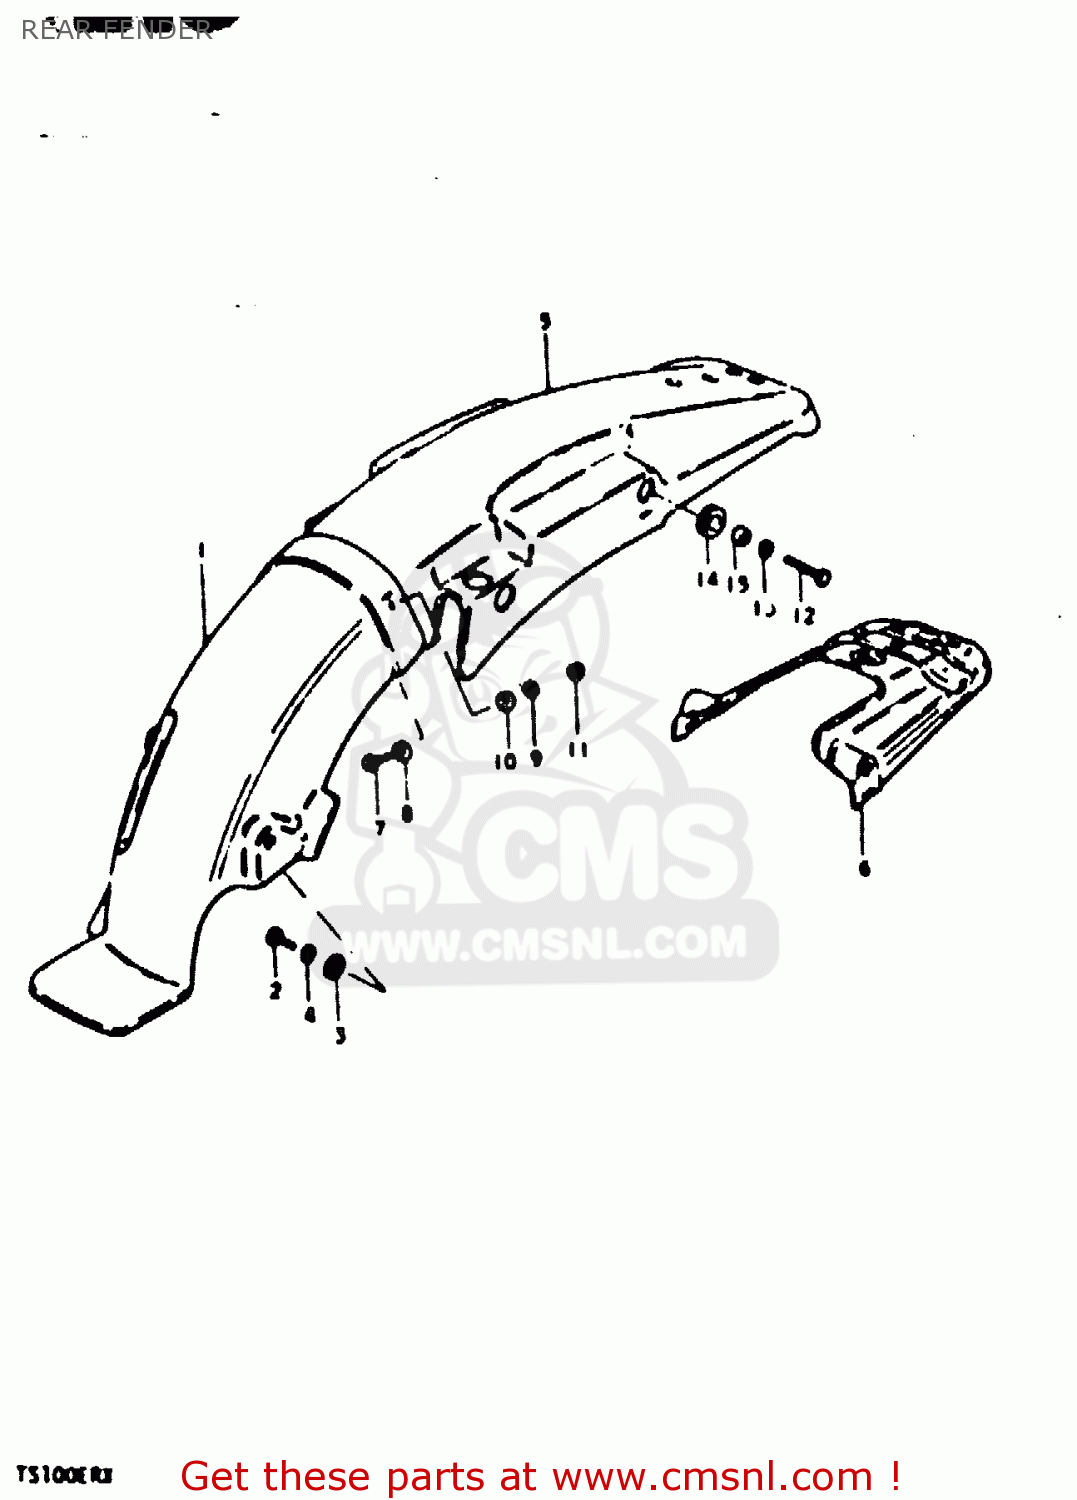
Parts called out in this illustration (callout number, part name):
1	BODY,REAR FENDER,FRONT
2	BOLT, UPPER
3	WASHER
4	LOCK WASHER
5	FENDER, REAR
6	REINFORCEMENT,RR FENDER
7	BOLT
8	WASHER (5.5X16X1.2)
9	LOCK WASHER
10	WASHER(5.2X16X1)
11	NUT
12	BOLT (8X30)
13	LOCK WASHER
14	CUSHION
15	SPACER (8.2X12X7.5)
